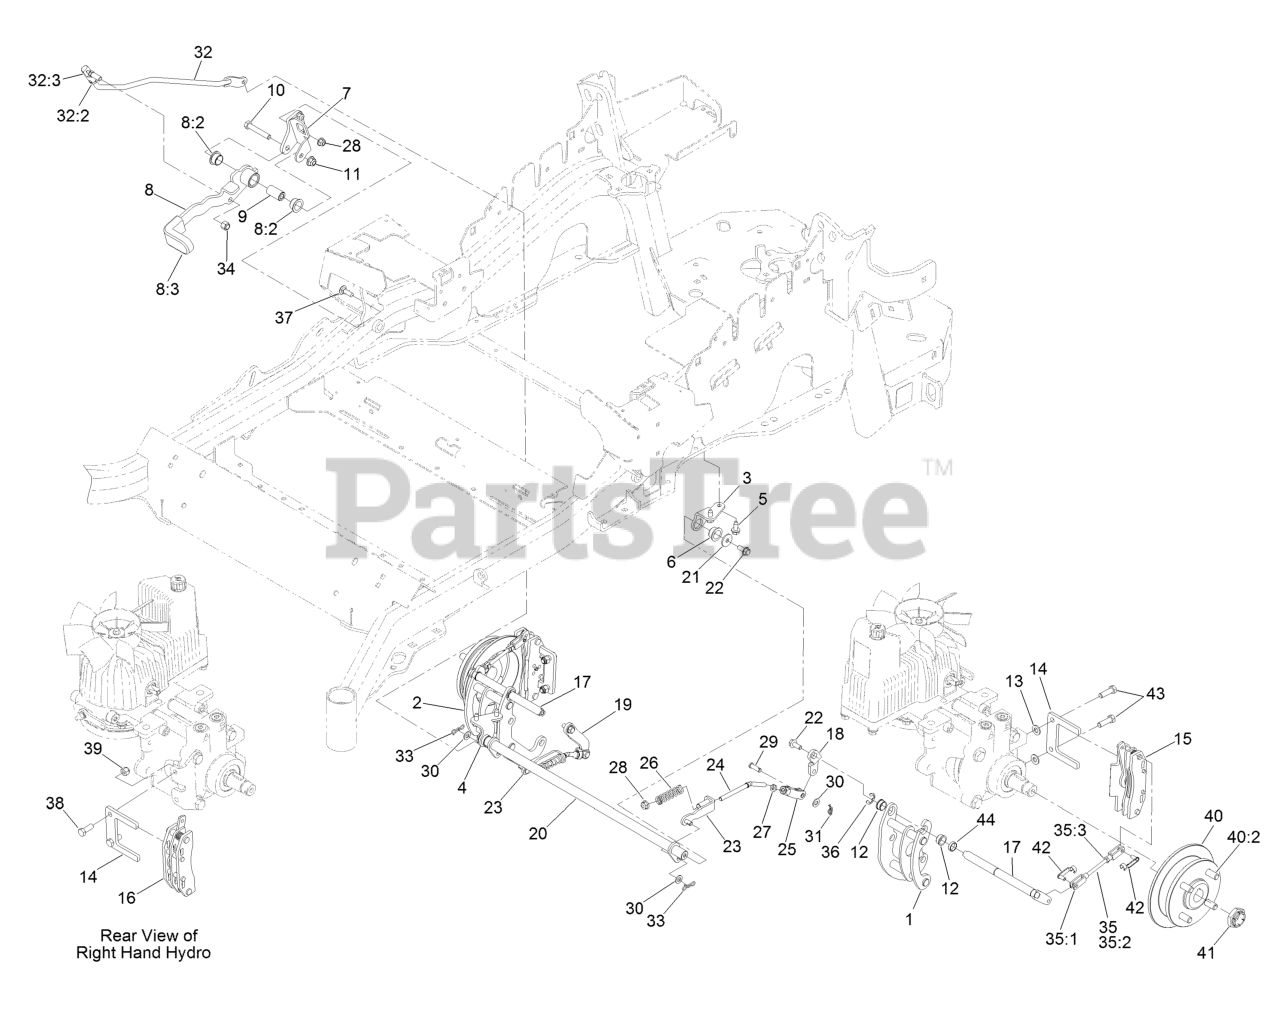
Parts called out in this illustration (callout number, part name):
1	Mount-Bellcrank, LH
2	Mount-Bellcrank, RH
3	Mount-Pivot, LH
4	Mount-Pivot, RH
5	Screw-HWHTF
6	Bushing-Flange
7	Bracket-Mount
8	Brake Lever ASM W/ Grip
8:2	Bushing-Flange
8:3	Grip-Lever
9	Handle-Pivot, Brake
10	Screw-HH
11	Nut-HF, NI
12	Bushing
13	Washer-Flat
14	Plate-Mount, Brake
15	Caliper-Brake
16	Caliper-Brake, RH
17	Bellcrank
18	Arm-Inner, LH
19	Arm-Inner, RH
20	Shaft-Cross
21	Washer-Flat
23	Bracket-L
24	Linkage-Mid
25	Yoke-Offset
26	Spring-Compression
27	Nut-Jam
28	Nut-HF, NI
29	Pin-Clevis
30	Washer-Plain
31	Pin-Cotter, Locking
32	Front Linkage ASM
32:2	End-Tie Rod, RH
32:3	Nut-HJ
33	Pin-Cotter, Locking
34	Nut-Lock
35	Rear Linkage ASM
35:1	Yoke
35:2	Linkage, Rear
35:3	Nut-Jam
37	Bolt-CARR
38	Screw-HH
39	Nut-Lock, NI
40	Wheel Hub ASM
40:2	Stud-Wheel
41	Locknut
42	Pin-Clevis, Spring
43	Screw-Lock, Patch
